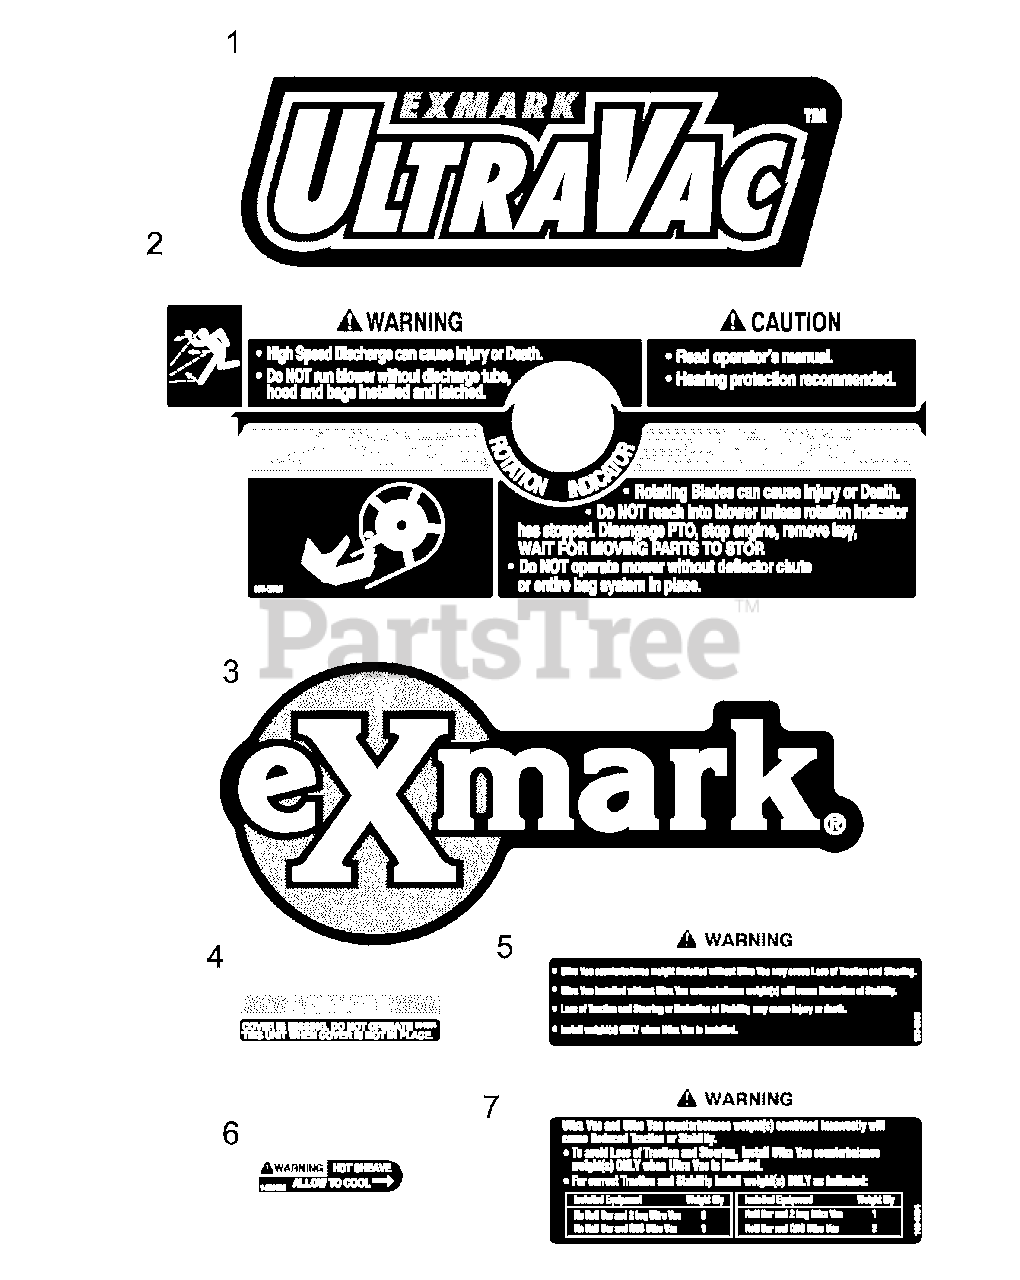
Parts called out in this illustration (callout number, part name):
1	DECAL, ULTRAVAC
2	DECAL-WARNING
3	DECAL, EXMARK LOGO
4	DECAL-COVER, MISSING
5	DECAL,WEIGHT
6	DECAL-WARNING
7	DECAL,WEIGHT
